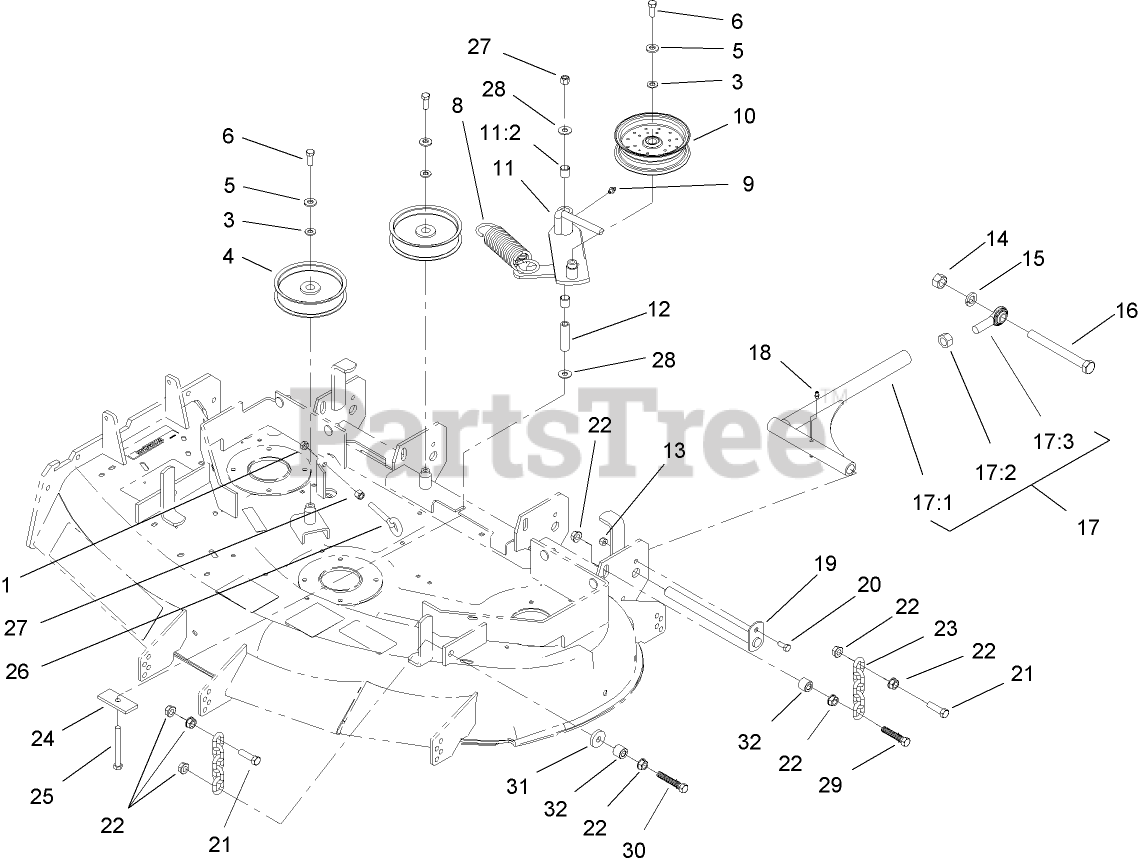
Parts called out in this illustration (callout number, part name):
1	NUT-HEX
3	WASHER-FLAT
4	PULLEY-IDLER
5	WASHER-BELLEVILLE
6	SCREW-HH
8	Spring-Extension
9	FITTING-GREASE, 90 DEG
10	PULLEY-IDLER, FLAT
11	IDLER ARM ASM
11:2	SLEEVE-BEARING
12	BUSHING-PIVOT, IDLER
13	NUT-LOCK, NI
14	NUT-HEX
15	WASHER-LOCK
17	STRUT ASM
17:1	STRUT
17:2	NUT-HEX
17:3	BALLJOINT-SPHERICAL
18	FITTING-GREASE
19	PIN-STRUT
20	SCREW-HH
21	SCREW-HH
22	NUT-HF
23	CHAIN-LIFT, DECK
24	PLATE-RETAINER, BOLT
25	SCREW-HH
26	BOLT-EYE
27	NUT-LOCK, NI
28	WASHER-HARDENED
29	SCREW HH
30	SCREW HH
31	WASHER
32	SPACER-BEDBAR
